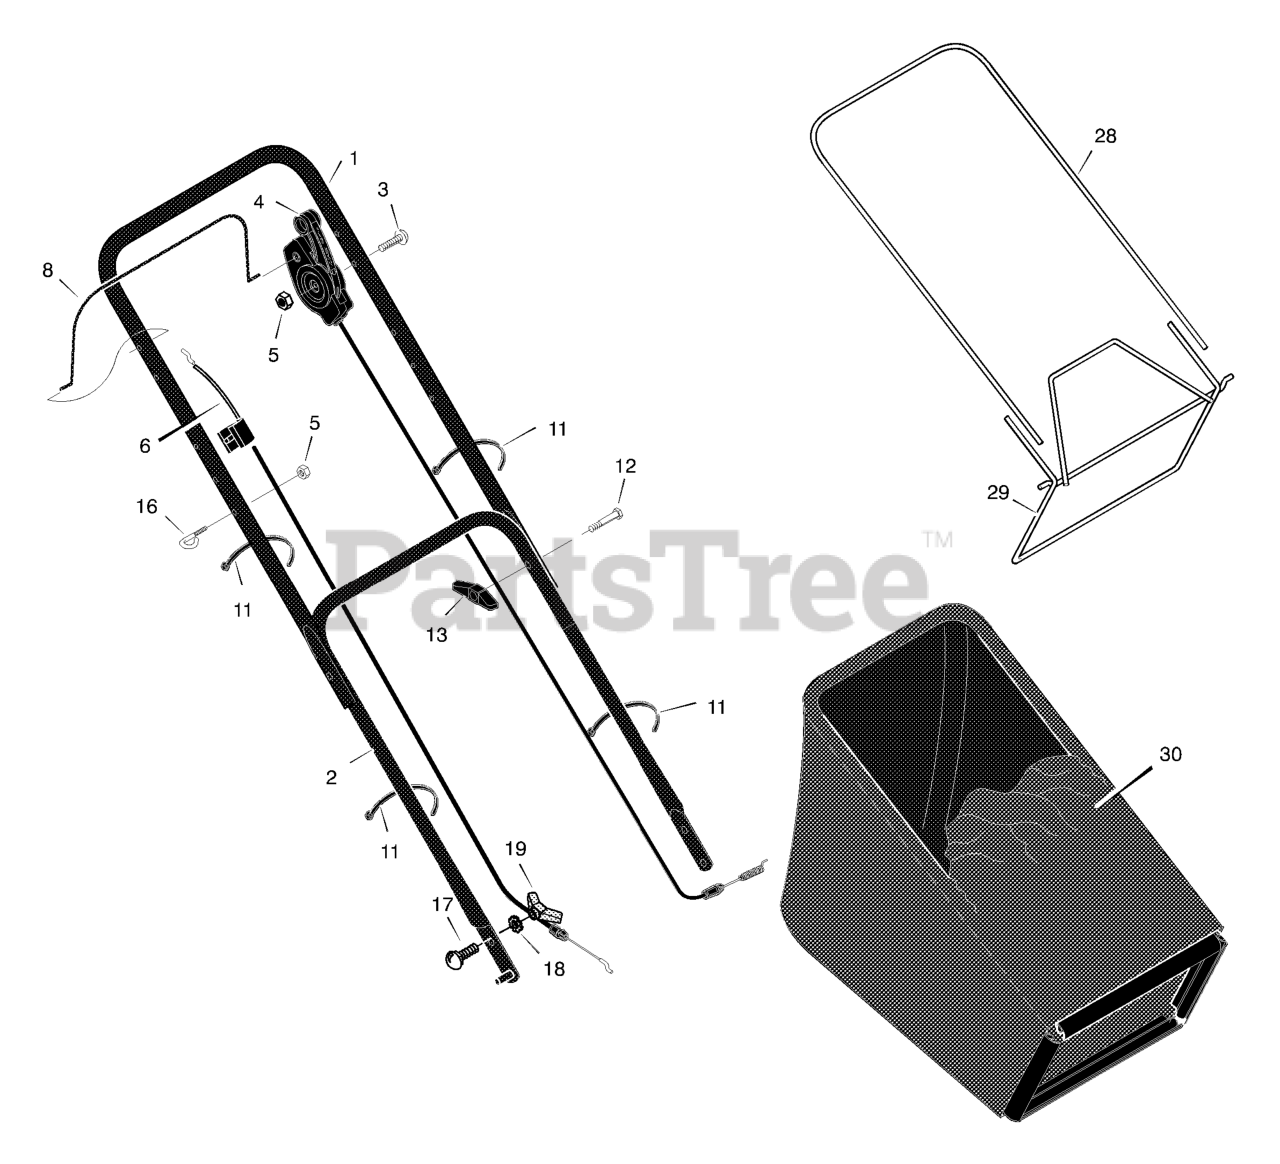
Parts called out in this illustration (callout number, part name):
1	Handle, Upper
2	Handle, Lower
4	Control, Drive
5	Locknut
6	Cable, Stop
8	Engine Stop Lever
11	Fastener, Cable
13	Knob
16	Guide, Rope
17	Bolt, Carriage
18	Washer
19	Knob, Plastic
28	Frame, Top
29	Frame Assembly
30	Bag, Cloth
